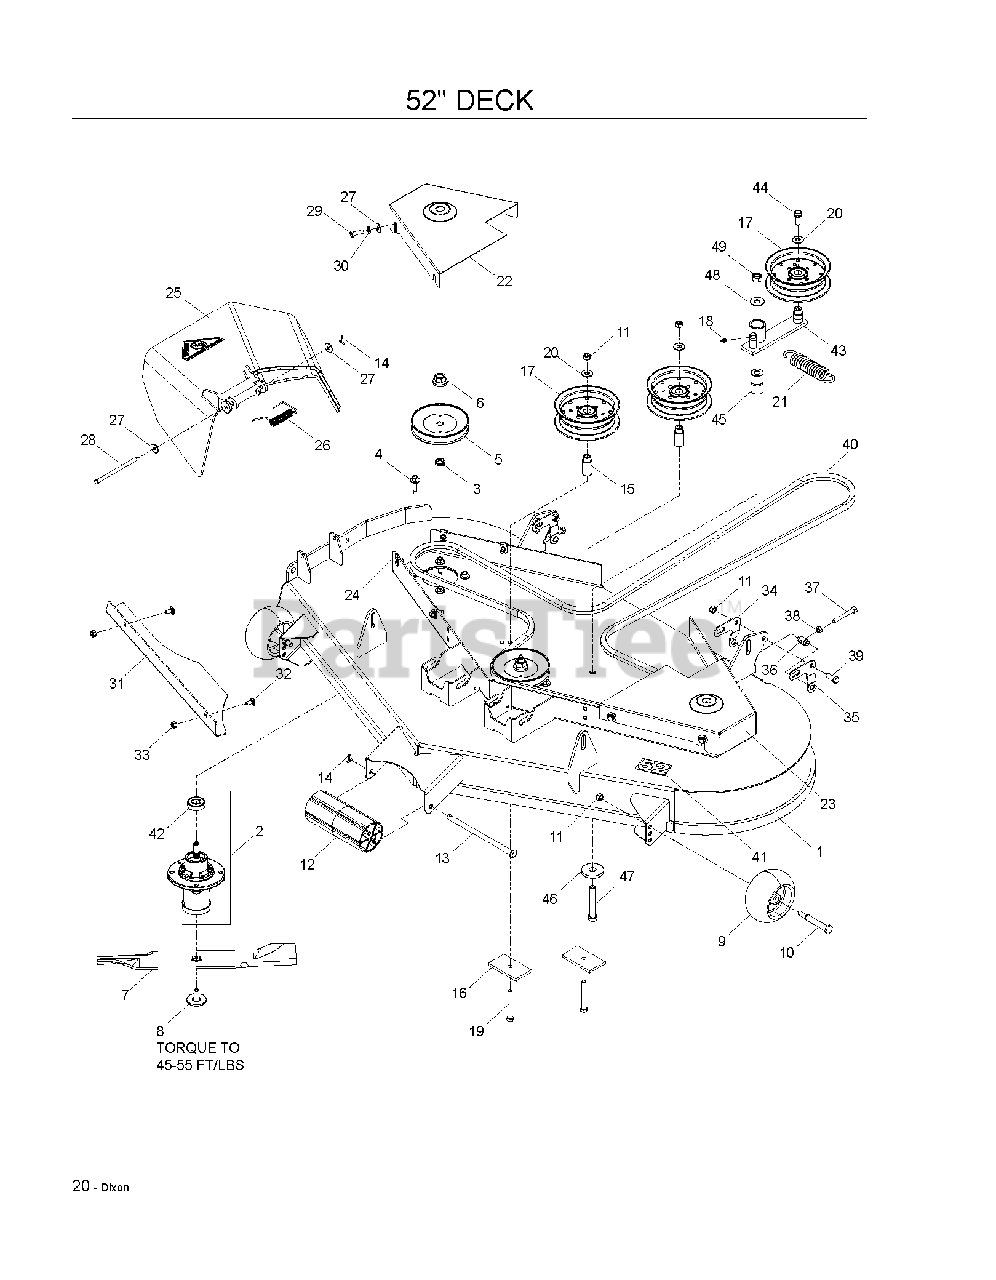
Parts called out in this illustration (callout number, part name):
1	DECK.FAB.W/DECALS.52".BLUE
2	MANDREL.DECK.ASSEMBLY
3	WASHER-SPACER
4	WASHER HEAD SCREW
5	PULLEY
6	LOCKNUT - 9/16
7	BLADE, 18"
8	BLADE BOLT ASSY-7/16" TB REPL
9	GAUGE WHEEL
10	SHOULDER BOLT 1/2X2-5/8 ZD SPE
11	NUT 3/8-16 NYLOC
12	NOSE ROLLER 48"
13	NOSE ROLLER ROD
14	COTTER PIN 1/8 X 3/4
15	IDLER BUSHING
16	SUPPORT PLATE
17	PULLEY, IDLER
18	ZERK
19	HCS 3/8C X 3
20	WASHER 3/8 FLAT
22	SHIELD, BELT 52 BLUE RH
23	SHIELD, BELT 52 BLUE LH
24	U-CLIP 5/16-18 NUT RETAINER
25	DISCHARGE CHUTE 52"
26	SPRING - TORSION
27	WASHER 5/16 FLAT
28	PIN-CLEVIS 5/16 DIA X 5.19 ZD
29	HCS 5/16C X 1
30	WASHER 5/16 LOCK
31	CONFINEMENT PLATE, 52"
32	CARRIAGE BOLT 5/16C X 5/8"
33	NUT 5/16 NYLOC
34	PITCH, ADJUST, RT
35	PITCH, ADJUST, LT
36	TRUNION, PITCH
37	HCS 5/16-18 X 2 1/2 TPBLT
38	NUT 5/16C HEX
39	HCS 3/8C X 1
40	BELT-DECK, 52
41	DECAL, 52"
42	BEARING, BALL
43	IDLER ARM
44	HCS 3/8C X 1 SERRATED HEAD
45	PIVOT BUSHING
46	WASHER, SUPPORT
47	HCS 1/2C X 3 1/4
48	WASHER 1/2 FLAT
49	NUT 1/2-13 HEX NYLOC ZD
